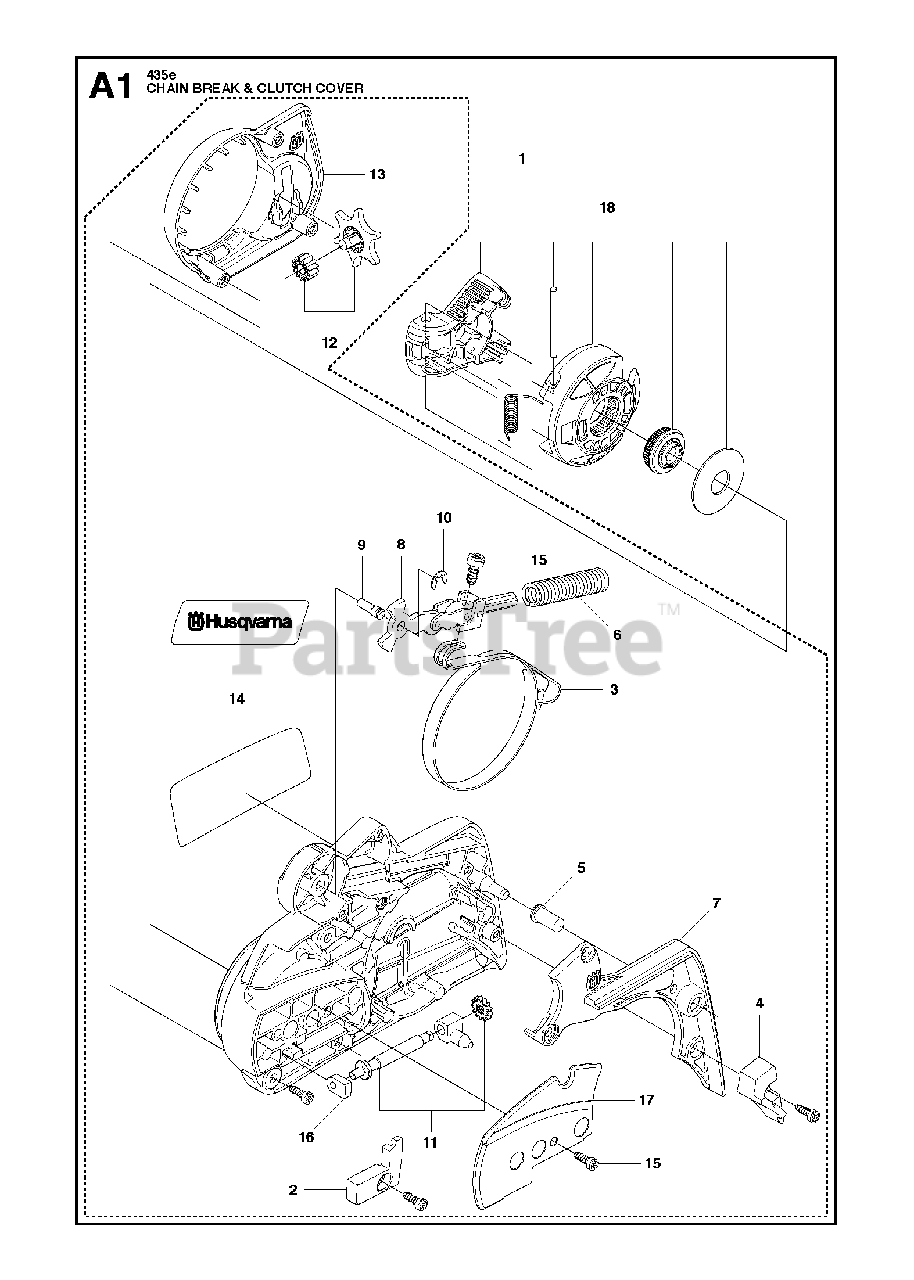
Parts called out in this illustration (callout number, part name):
1	ASSY CHAIN BRAKE HUSQ ORANGE
2	COVER
3	BRAKE BAND ASSY
4	WEAR PROTECTION
5	SLEEVE
6	BRAKE SPRING
7	COVER
8	JOINT
9	PIN
10	E-RING 4
11	CHAIN TENSIONER SCREW, COMP.
12	CHAIN TENSIONER WHEEL, COMP.
13	HEAT SHIELD
14	DECAL, CLUTCH HOUSING
15	SCREW
16	BEARING SLEEVE
17	WEAR PLATE
18	KNOB, COMPLETE
